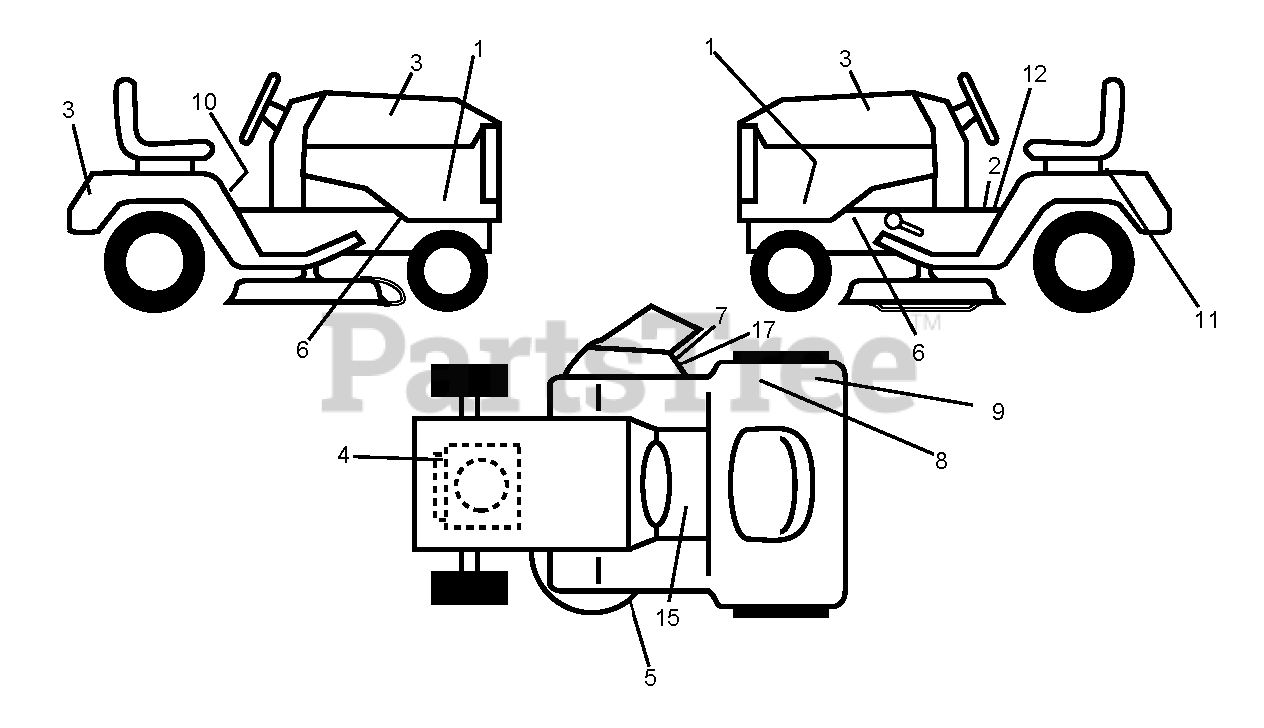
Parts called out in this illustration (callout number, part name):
2	DECAL PARK BRAKE
3	DECAL.HOOD.LOGO.ORANGE.HUSQVAR
4	DECAL
5	DECAL V BELT SCHEMATIC
7	DECAL.INTERNATIONL.CUTFINGER
8	DECAL 80 DBA
9	DECAL
10	LABEL
11	DECAL BTRY SYMBOLS
12	DECAL
15	DECAL
17	DECAL, DEFLECT WARNING
